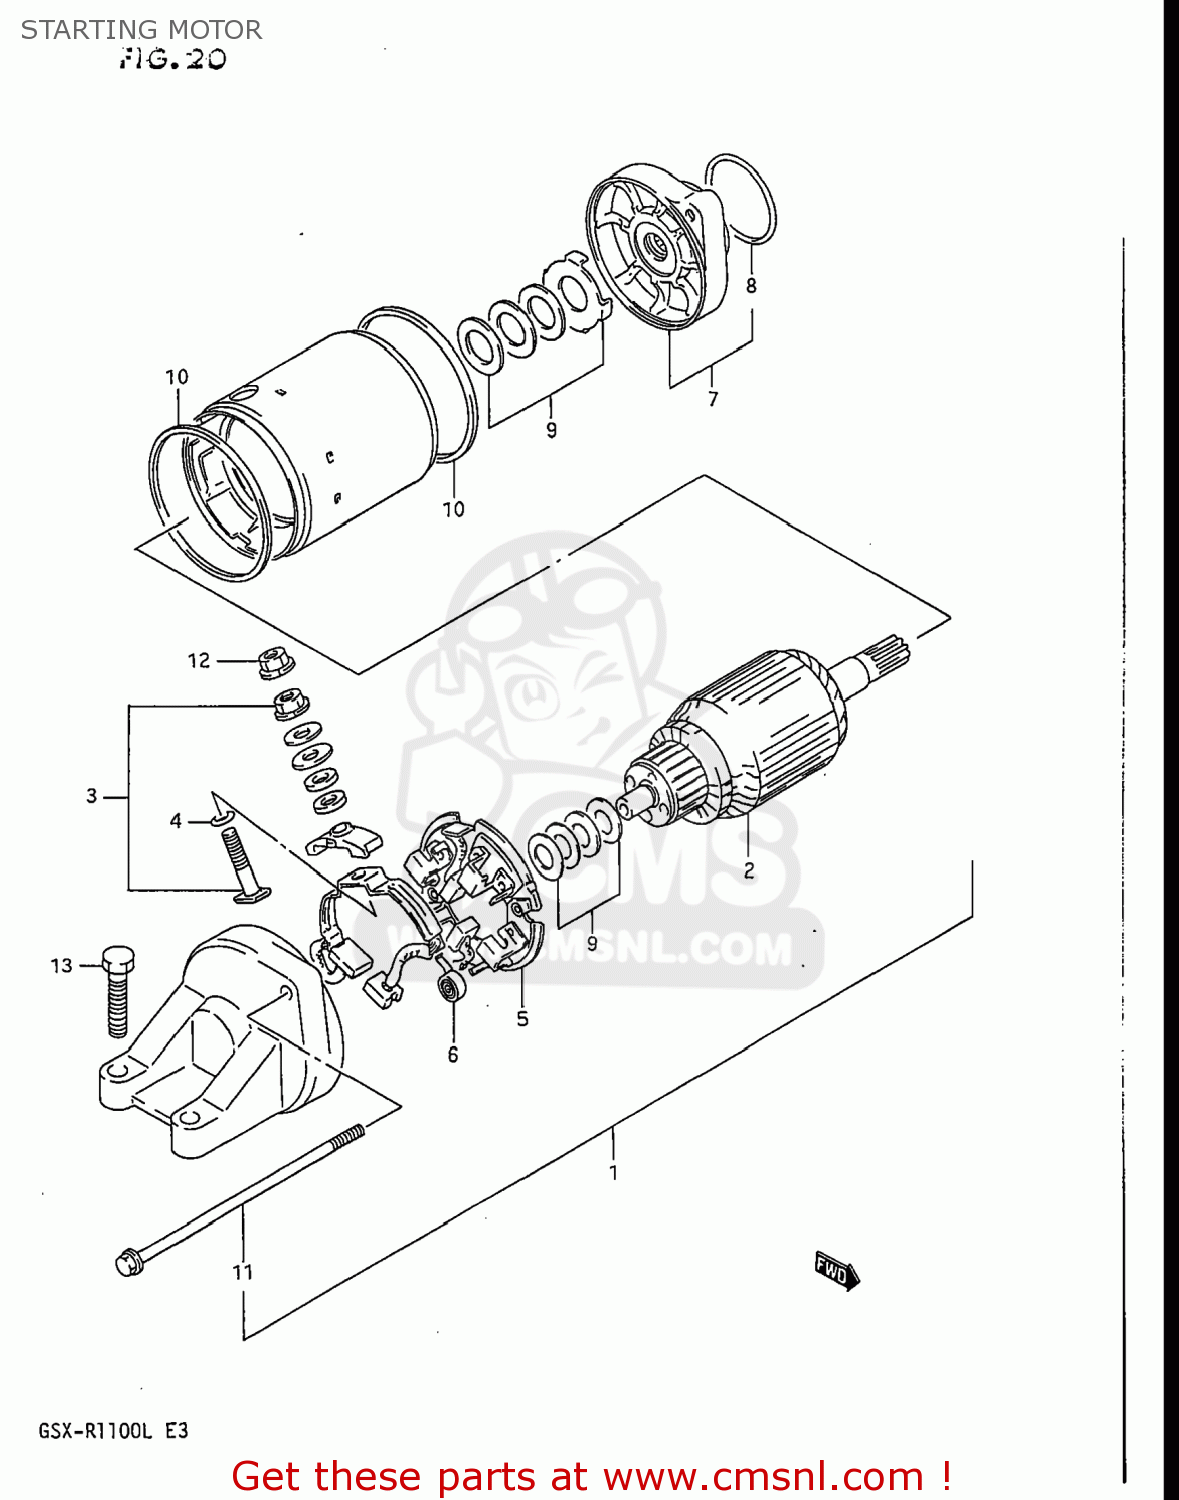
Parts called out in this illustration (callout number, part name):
1	MOTOR ASSEMBLY,STARTING
2	ARMATURE
3	TERMINAL SET,BRUSH
4	O RING
5	HOLDER SET,BRUSH
6	SPRING,BRUSH
7	BRACKET
8	O-RING
9	SHIM SET,STARTING MOTOR
10	O RING
11	BOLT
12	NUT
13	SCREW (6X25)
